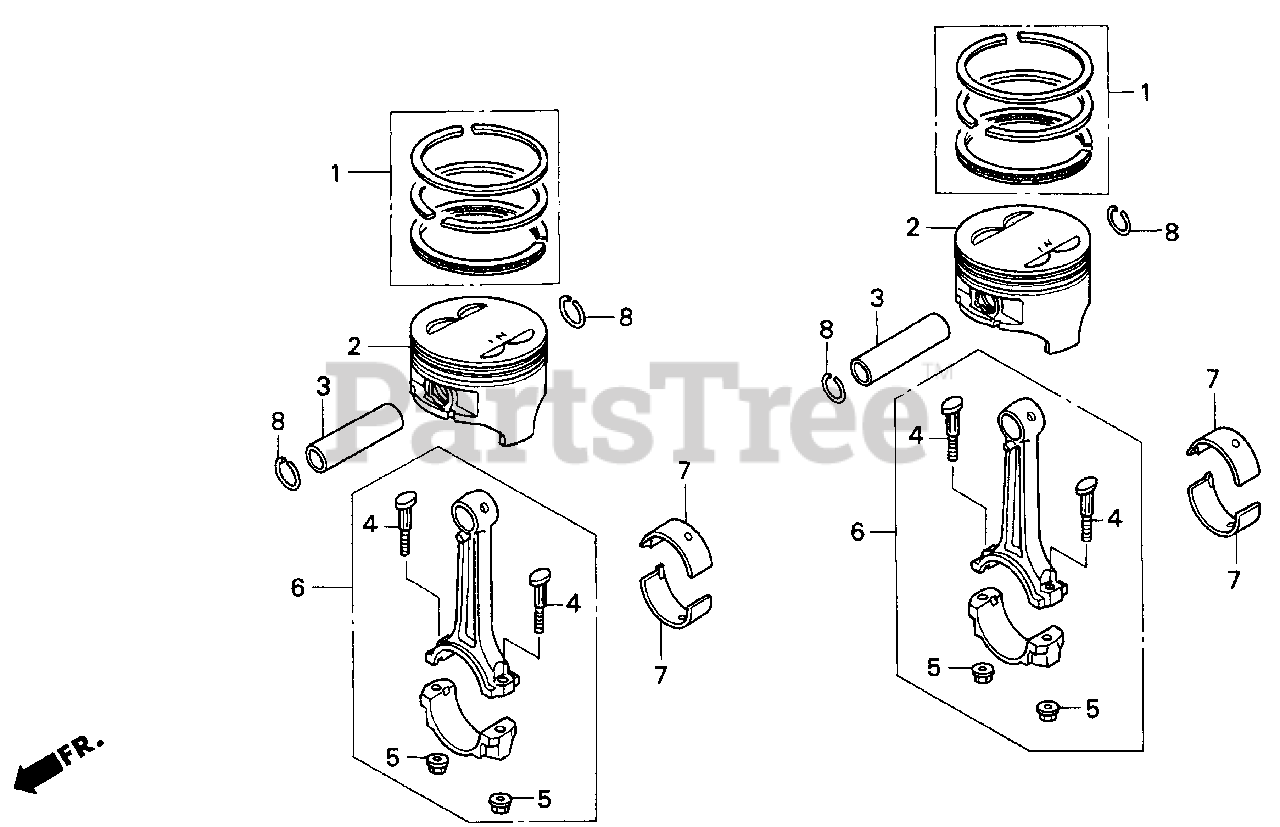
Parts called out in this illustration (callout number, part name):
1	RING SET, PISTON (STD)
1	RING SET, PISTON (OS 0.25)
1	RING SET, PISTON (OS 0.50)
2	PISTON (STD)
2	PISTON (OS 0.25)
2	PISTON (OS 0.50)
3	PIN, PISTON
4	BOLT, CONNECTING ROD (TOKAI TRW)
5	NUT, CONNECTING ROD
6	ROD ASSY., CONNECTING
7	BEARING A, CONNECTING ROD (BLUE)
7	BEARING B, CONNECTING ROD (BLACK)
7	BEARING C, CONNECTING ROD (BROWN)
7	BEARING D, CONNECTING ROD (GREEN)
7	BEARING E, CONNECTING ROD (YELLOW)
7	BEARING F, CONNECTING ROD (PINK)
7	BEARING G, CONNECTING ROD (RED)
8	CLIP, PISTON PIN (19MM)
